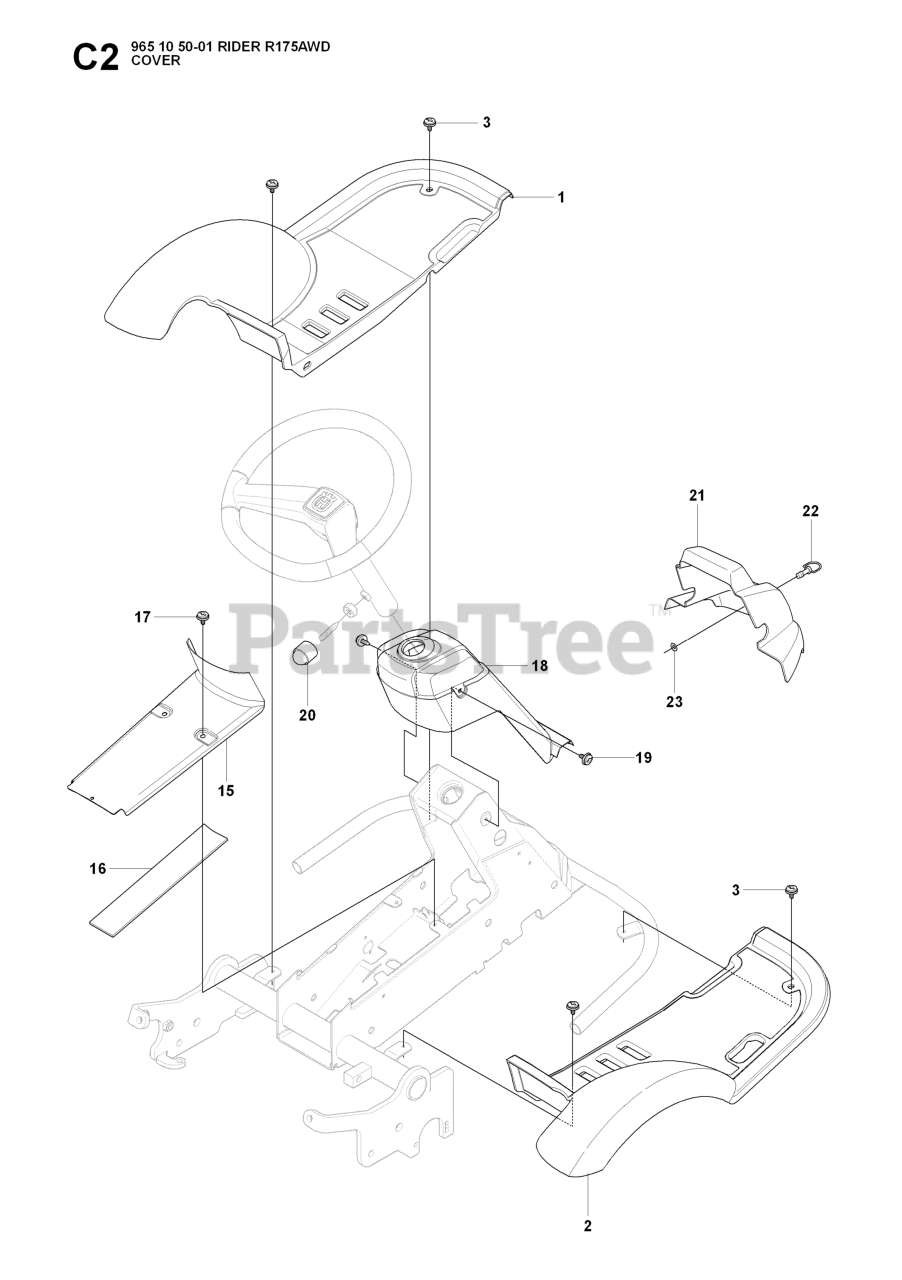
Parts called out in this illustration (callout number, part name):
1	FOOT PLATE
2	FOOT PLATE
20	PROTECTIVE COVER
22	BOLT
